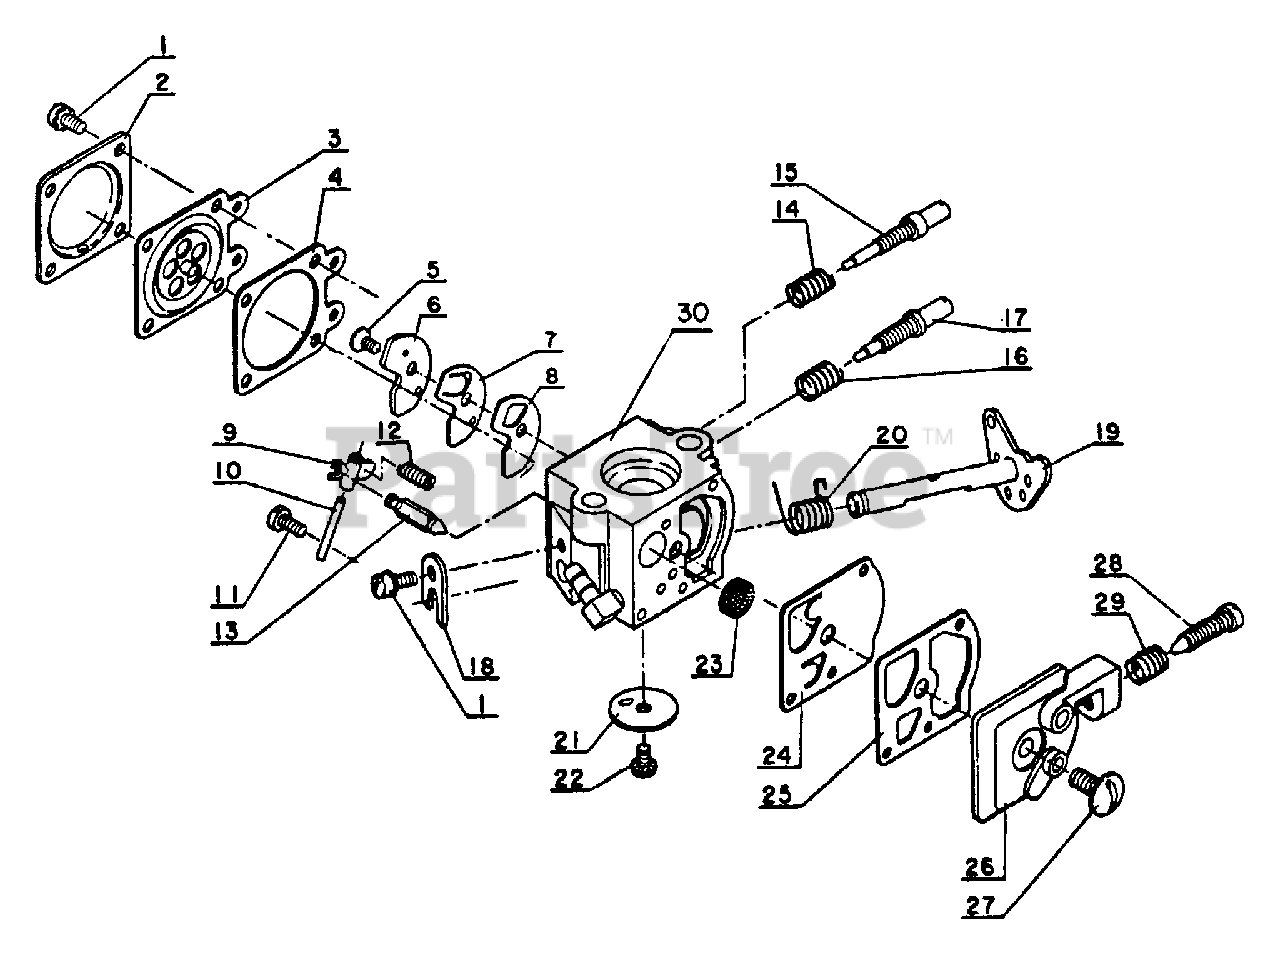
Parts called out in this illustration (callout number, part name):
2	COVER, METERING
3	DIAPHRAGM, METERING
4	GASKET, METERING
5	SCREW, CIRCUIT PLATE
6	PLATE, CIRCUIT
7	VALVE, CHECK
8	GASKET, CIRCUIT PLATE
9	LEVER, METERING
10	PIN, METERING LEVER
11	SCREW, METERING LEVER PIN
12	SPRING, METERING LEVER
13	VALVE, INLET NEEDLE
15	NEEDLE - HIGH SPEED
16	SPRING, IDLE ADJUST
17	NEEDLE - LOW SPEED
18	CLIP, THROTTLE SHAFT
19	SHAFT, THROTTLE
20	SPRING, THROTTLE RETURN
21	VALVE, THROTTLE
23	STRAINER
24	DIAPHRAGM, PUMP
25	GASKET, PUMP
26	COVER, PUMP
27	SCREW, PUMP COVER
28	SCREW, IDLE ADJUST
29	SPRING, IDLE ADJUST
30	BODY, CARBURETOR
